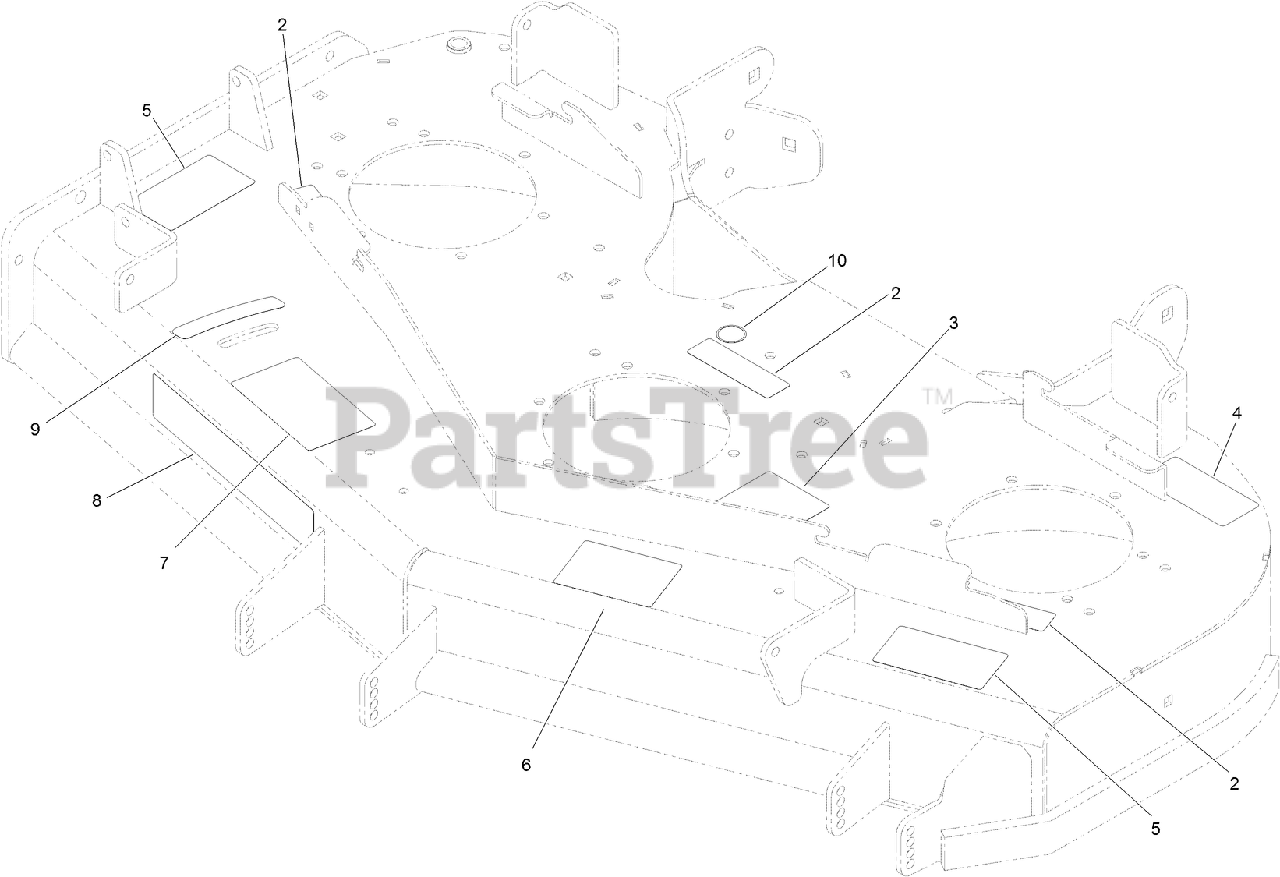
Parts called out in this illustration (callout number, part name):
2	DECAL-MISSING, COVER
3	DECAL-ROUTING, DECK BELT
4	DECAL-TORQUE, BLADE BOLT
5	DECAL-DANGER
6	DECAL-ANTI SCALP
7	DECAL-ADJUSTMENT, BAFFLE
9	DECAL-SETTING, BAFFLE
10	DECAL-GREASE
